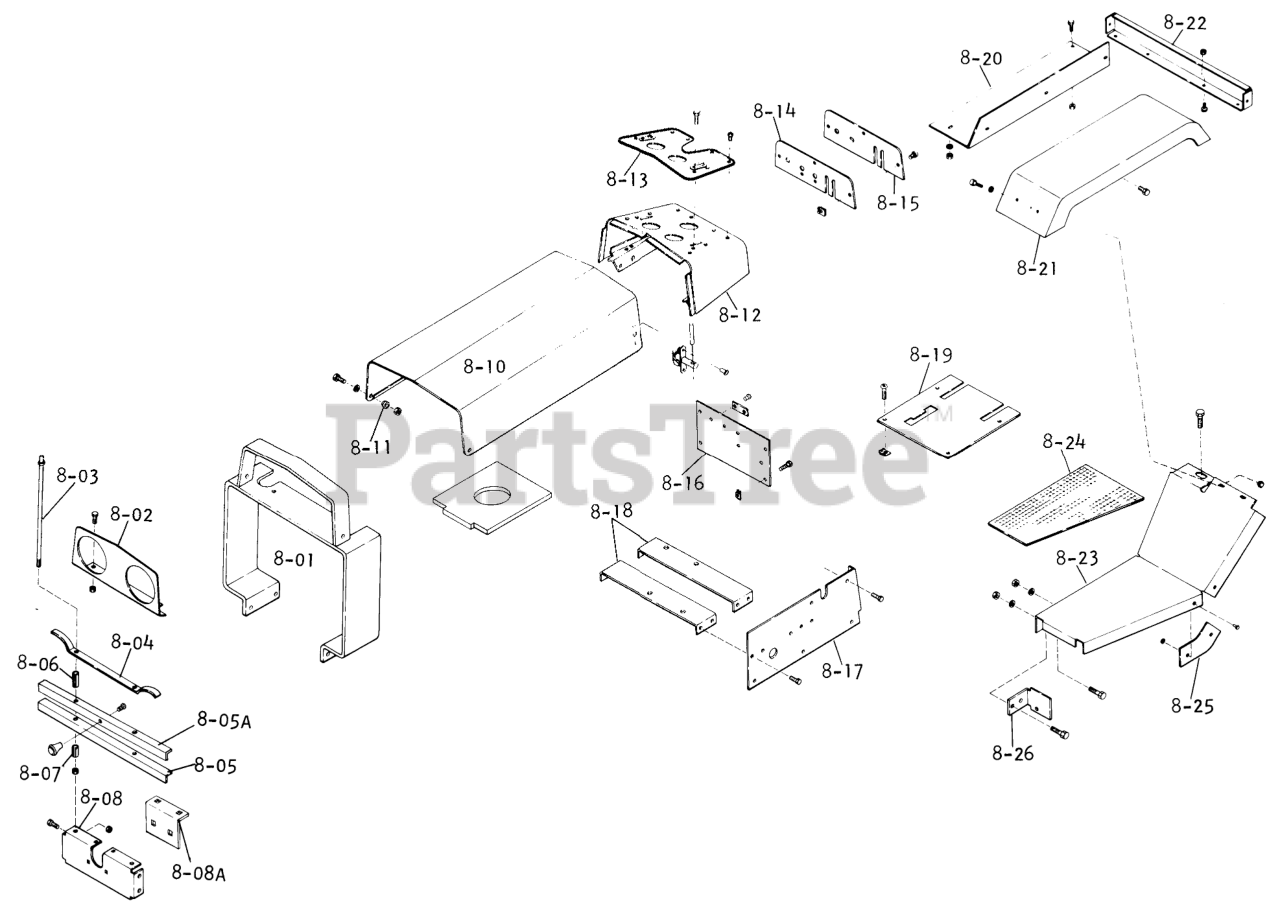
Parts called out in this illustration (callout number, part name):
8-01	Grille Shroud Assy.
8-02	Light Bracket
8-03	Rod-Grille
8-04	SPRING GRILLE
8-05	Grille
8-05A	Angle-Grille
8-06	Spacer-Grille 5/16 X 17/8
8-07	Spacer-Grille 5/16 X 11/4
8-08	Cover-Front
8-08A	Cover
8-10	Assy-Hood
8-11	Bushing
8-12	Selector Pin
8-13	Change Gear Shift
8-14	Idler Shaft
8-15	High Gear (19 teeth)
8-16	Panel, Console (Rear-Hyd. Valve Support)
8-17	Panel R.H. Console (Side)
8-18	Battery Support
8-19	Plate-Access Cover
8-20	Plate-R.H. Fender
8-21	Fender-Right and Left
8-22	Channel
8-23	Footrest-R.H.
8-24	Footrest Mat RH
8-25	Filler Plate
8-26	Bracket
